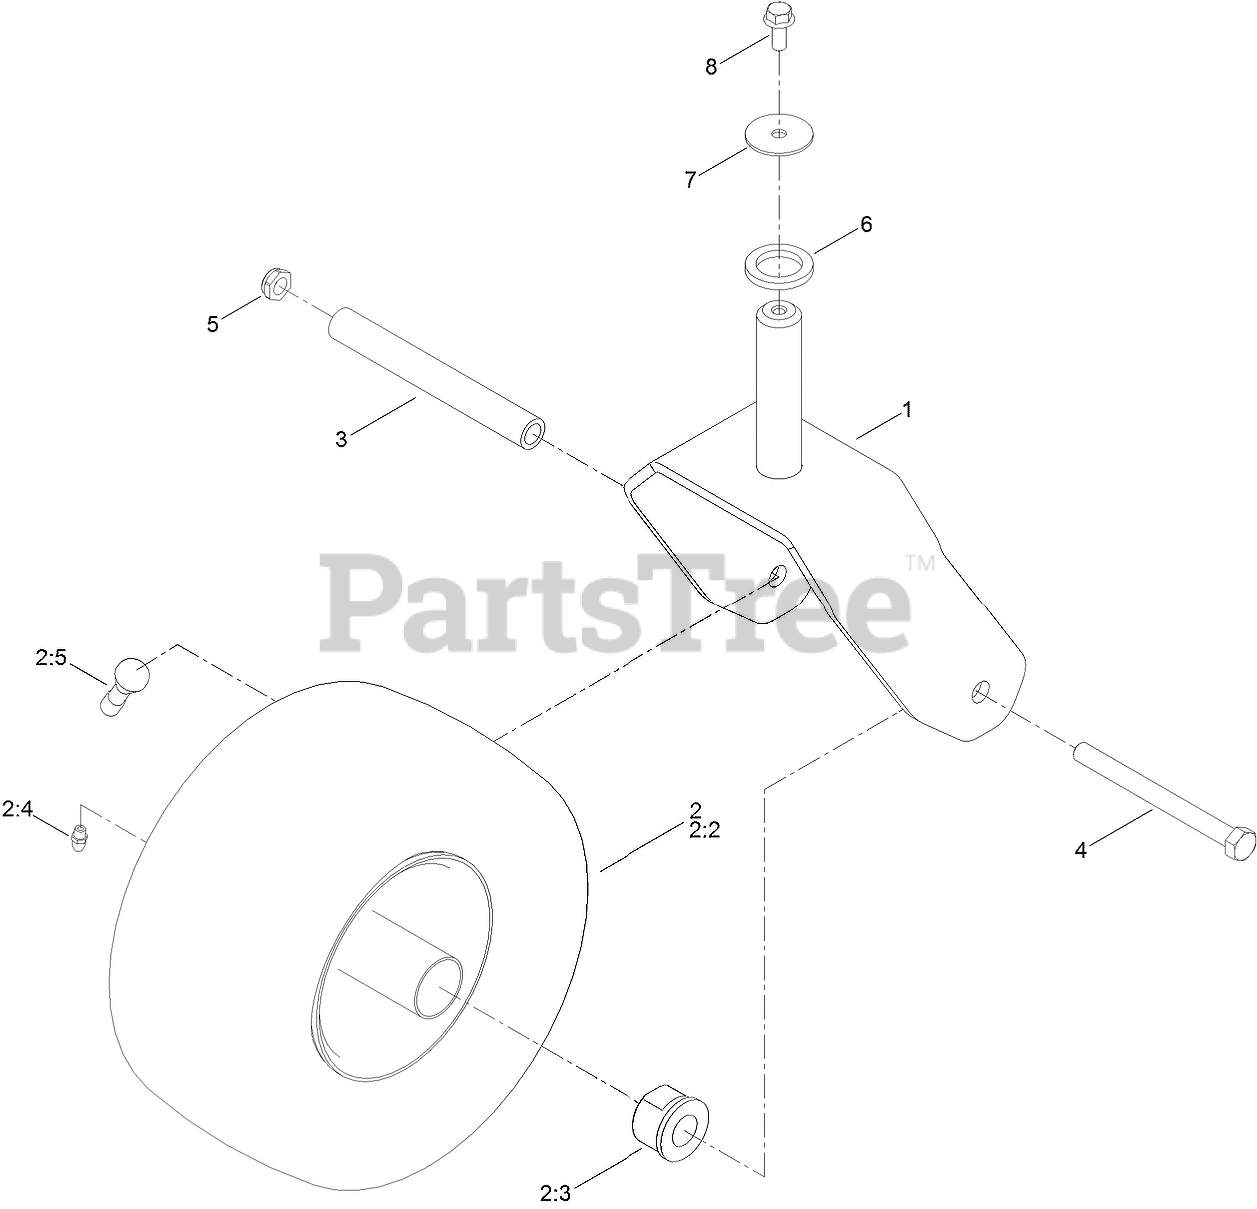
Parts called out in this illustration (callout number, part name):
1	FORK ASM
2	TIRE AND WHEEL ASM
2:3	BUSHING-FLANGE
2:4	FITTING-GREASE
3	SPACER-SPANNER
4	SCREW-HH
5	NUT-HEX
6	WASHER-THRUST
7	WASHER-FLAT
8	SCREW-HHF
